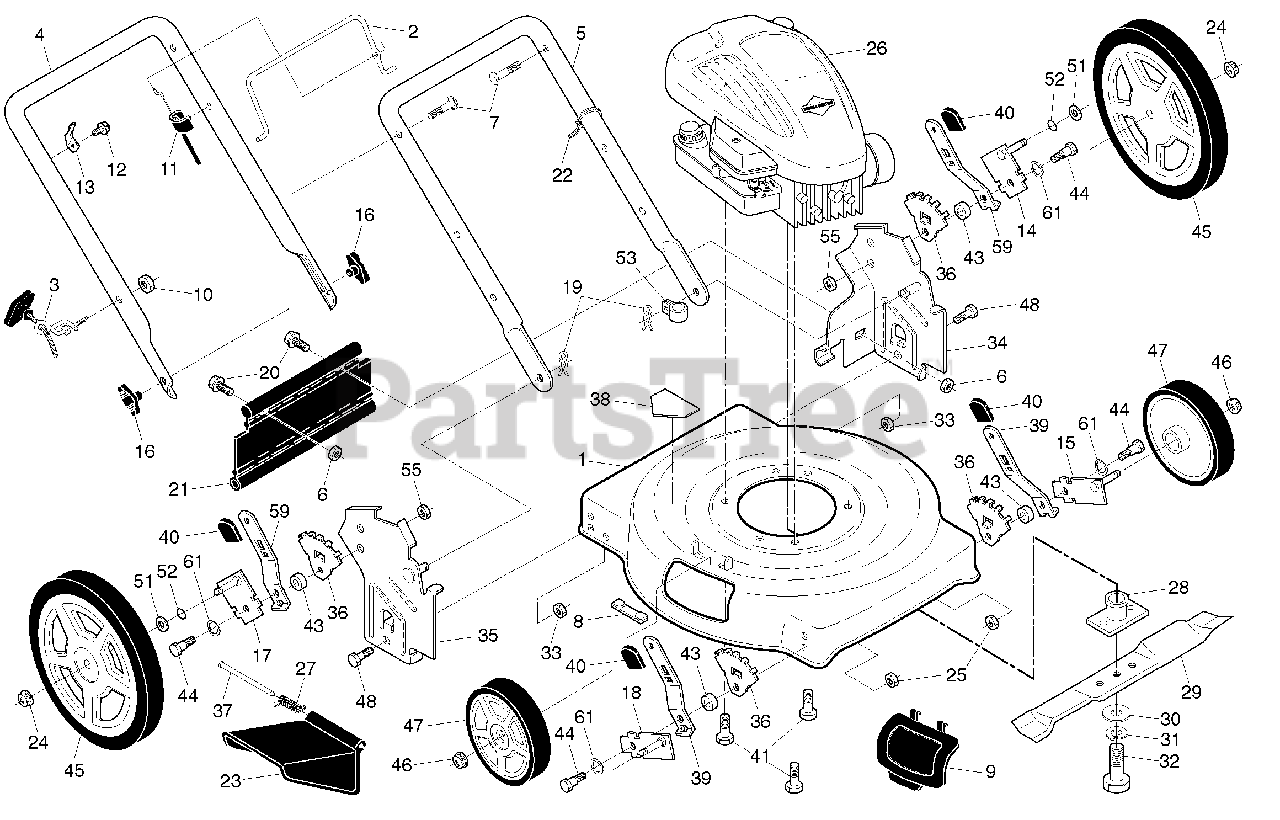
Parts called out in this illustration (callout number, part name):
1	Kit, Lawn Mower Housing
2	Control Bar
3	Rope Guide
4	Upper Handle
5	Lower Handle
6	Locknut, Hex 1/4-20
7	Handle Bolt 5/16-18
8	Clip, Closeout
9	Mulcher Plate
10	Nut, Hex 1/4-20
11	Engine Zone Control Cable
12	Hex Washer Head Screw #10-24 x 1/2
13	Up-Stop Bracket
14	Axle Arm Assembly, Rear, LH
15	Axle Arm Assembly, Front, LH
16	Knob, Handle
17	Axle Arm Assembly, Rear, RH
18	Axle Arm Assembly, Front, RH
19	Hairpin Cotter
20	Screw, Hex Cap Head 1/4-20
21	Rear Deflector
22	Wire Tie
23	Discharge Guard
24	Nut, Hex, Flangelock 3/8-16
25	Nut, Hex, Flangelock 5/16-18
27	Torsion Spring
28	Blade Adapter
29	22" Blade
30	Hardened Washer
31	Helical Lockwasher 3/8
32	Screw, Hex Head, Grade 8, 3/8-24 x 1-3/8
33	Nut, Hex, Nylock 5/16-18
34	Handle Bracket, LH
35	Handle Bracket, RH
36	Wheel Bracket Adjuster
37	Hinge Rod
38	Danger Decal
39	Selector Spring, Front
40	Selector Knob
41	Screw, Hex Head, Threaded, Rolled 3/8-16 x 1
43	Spacer
44	Shoulder Bolt 5/16-18
45	Wheel & Tire Assembly, Rear, 12"
46	Nut, Hex, Flangelock 3/8-16
47	Wheel & Tire Assembly, Front, 7"
48	Bolt, Hex Head 5/16-18
51	Washer, Flat 3/8
52	O-Ring
53	Clip, Cable
55	Nut, Hex
59	Selector Spring, Rear
61	Washer, Curved, Cylindrical
61	Operator's Manual, English
61	Operator's Manual, French
61	Repair Parts Manual
